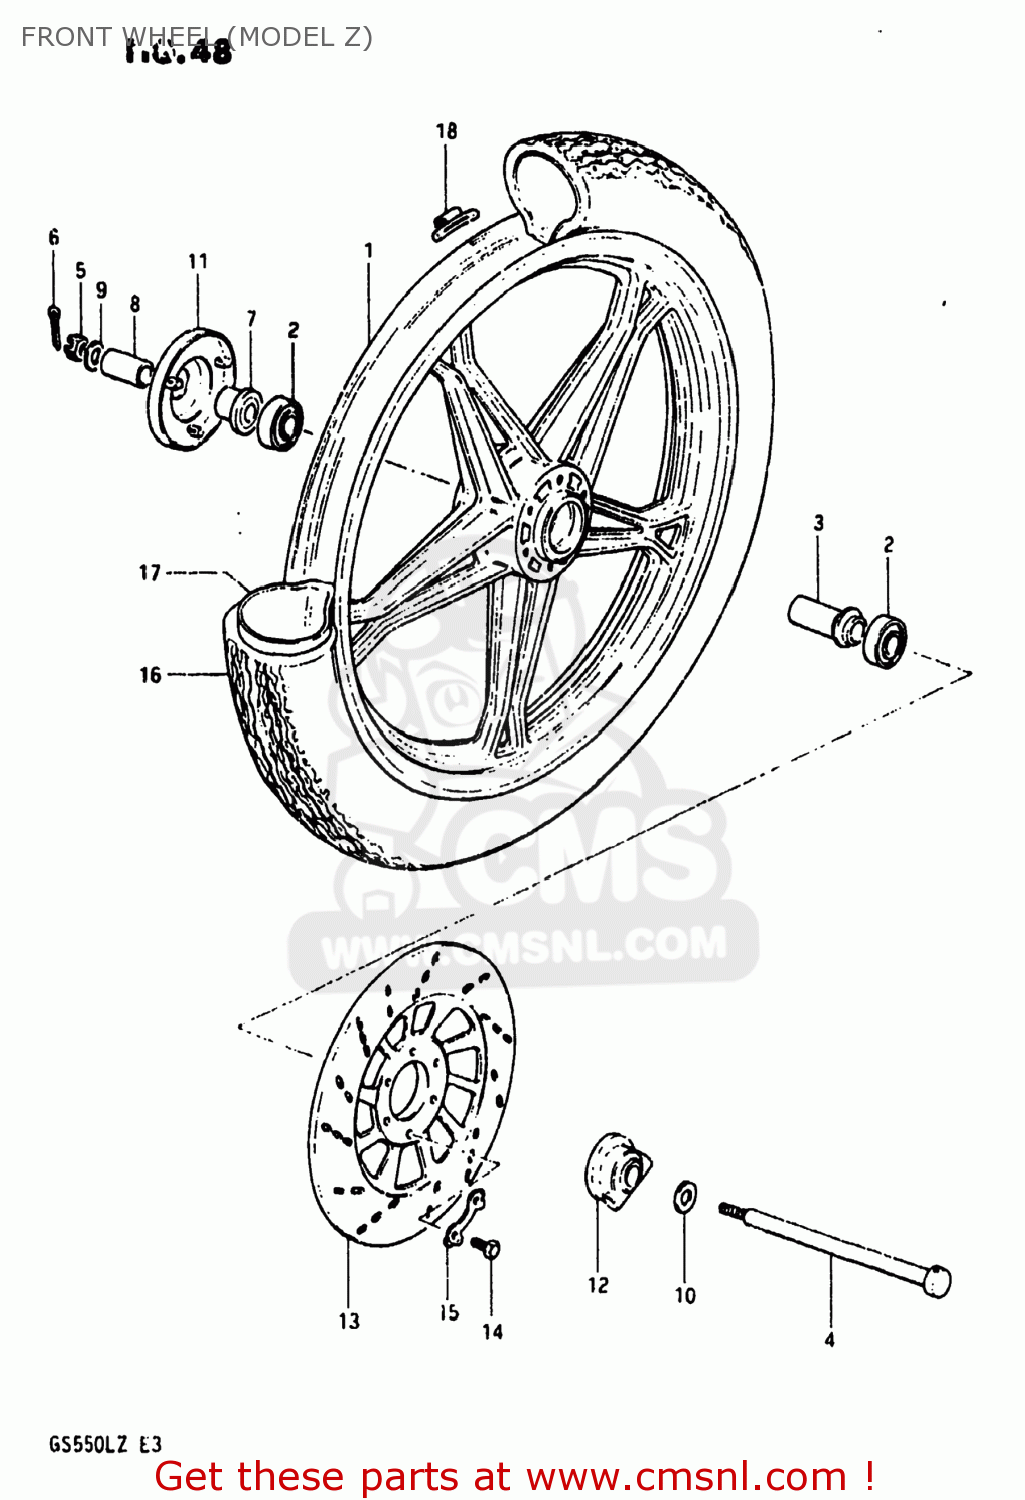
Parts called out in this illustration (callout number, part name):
1	CASTING WHEEL,FRONT 1.85
2	BEARING
3	SPACER,FR HUB BEARING
4	AXLE,FR
5	NUT 12MM
6	COTTER PIN
7	SPACER,FR AXLE,R
8	SPACER
9	WASHER
10	WASHER(15.5X26X2.3)
11	COVER,FR HUB,R
12	BOX ASSEMBLY,SPEEDOMETER GEAR
13	DISC,BRAKE
14	BOLT(8X25)
15	WASHER
16	TIRE,FRONT
17	TUBE 2.75-19 070-483MM
18	BALANCER,WHEEL
